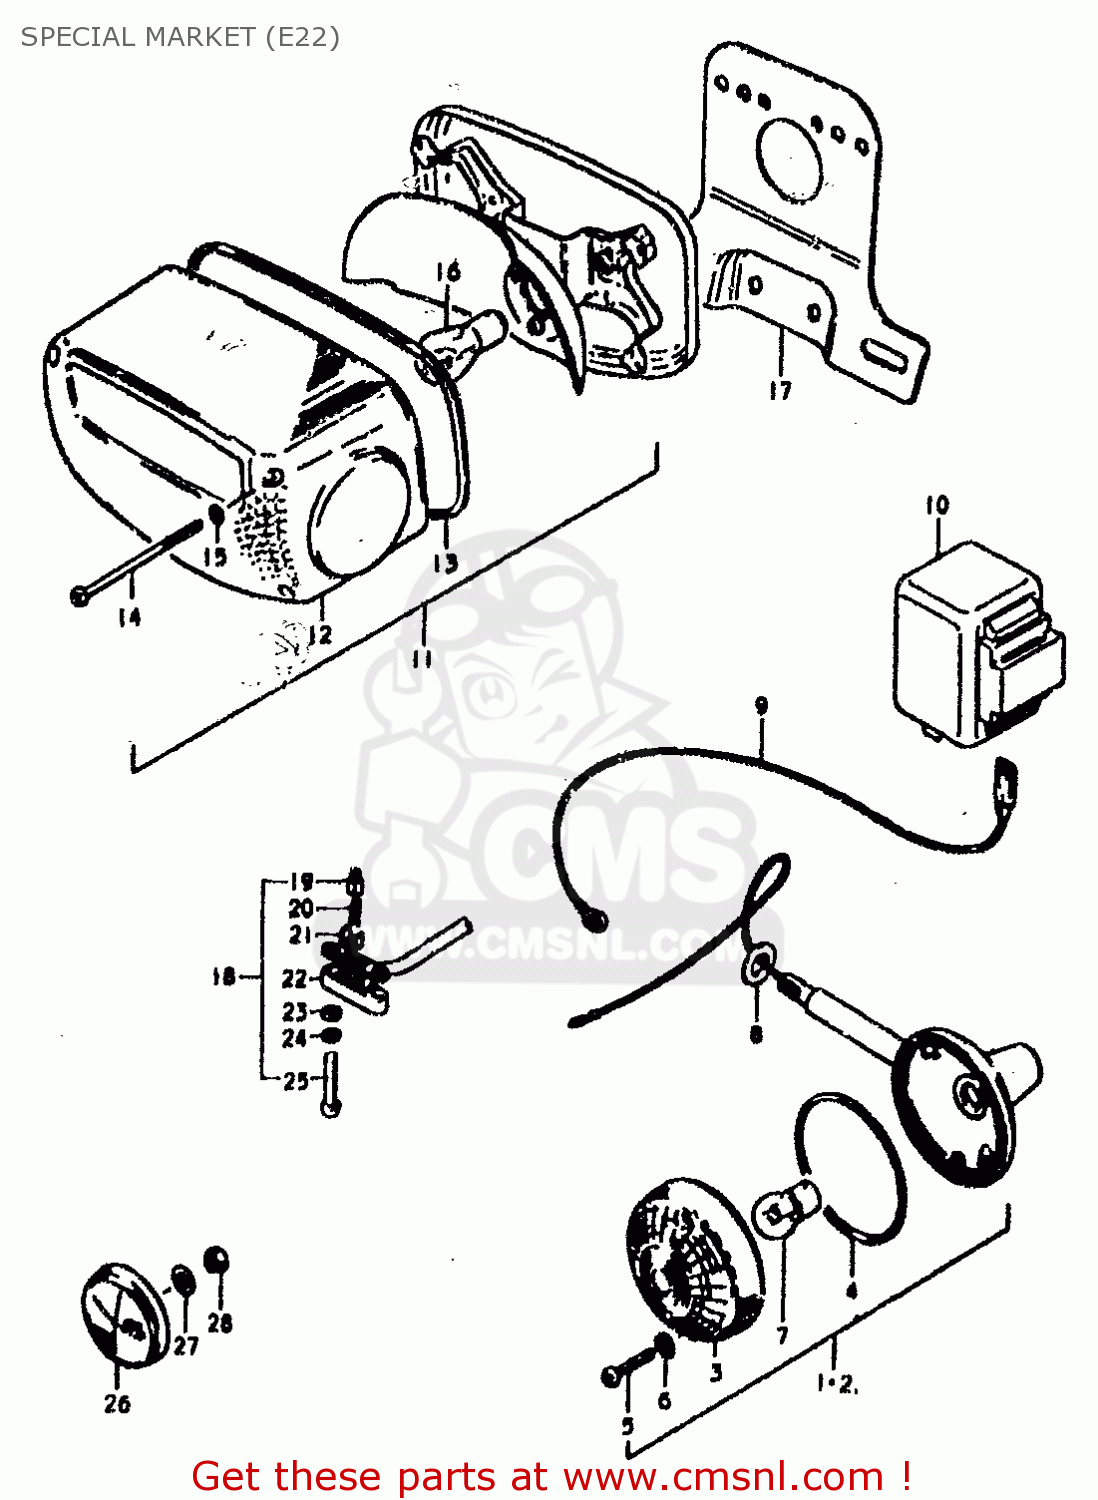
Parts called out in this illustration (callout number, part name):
1	LAMP ASSY,FRONT TURN SIGNAL
2	LAMP ASSY,REAR TURN SIGNAL
3	LENS
4	GASKET (NAS)
5	SCREW 4X25
6	GASKET (NAS)
7	BULB(12V21W)
8	WASHER(10.5X24X1)
9	LEAD WIRE,TURN SIGNAL RELAY (-)
10	RELAY, TURN SIGNAL
11	LAMP ASSY, REAR COMBINATION
12	LENS,RR COMBIN
13	GASKET (NAS)
14	SCREW (4X55)
15	GASKET (NAS)
16	BULB(12V21/5W)
17	PLATE,LICENCE
18	SWITCH ASSY,STOP
19	HOLDER
20	SPRING
21	PLATE
22	COVER,FR BK TERMINAL BASE
23	WASHER
24	LOCK WASHER
25	SCREW
26	REFLECTOR,REFLEX
27	WASHER
28	NUT
